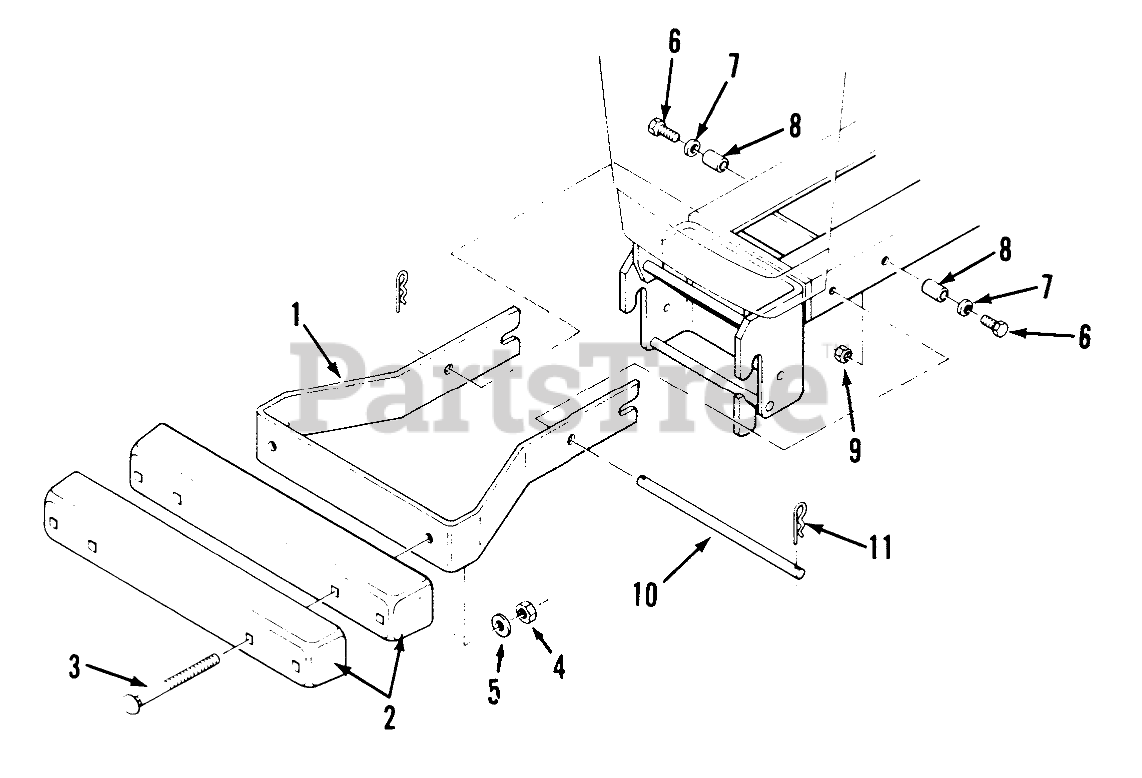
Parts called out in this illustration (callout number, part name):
1	FRAME-WEIGHT R
2	FRONT WEIGHT B
3	Bolt-Carriage
4	Nut
5	WASHER
6	Bolt
7	Washer
8	SPACER
9	NUT
10	ROD
11	Hairpin Cotter
